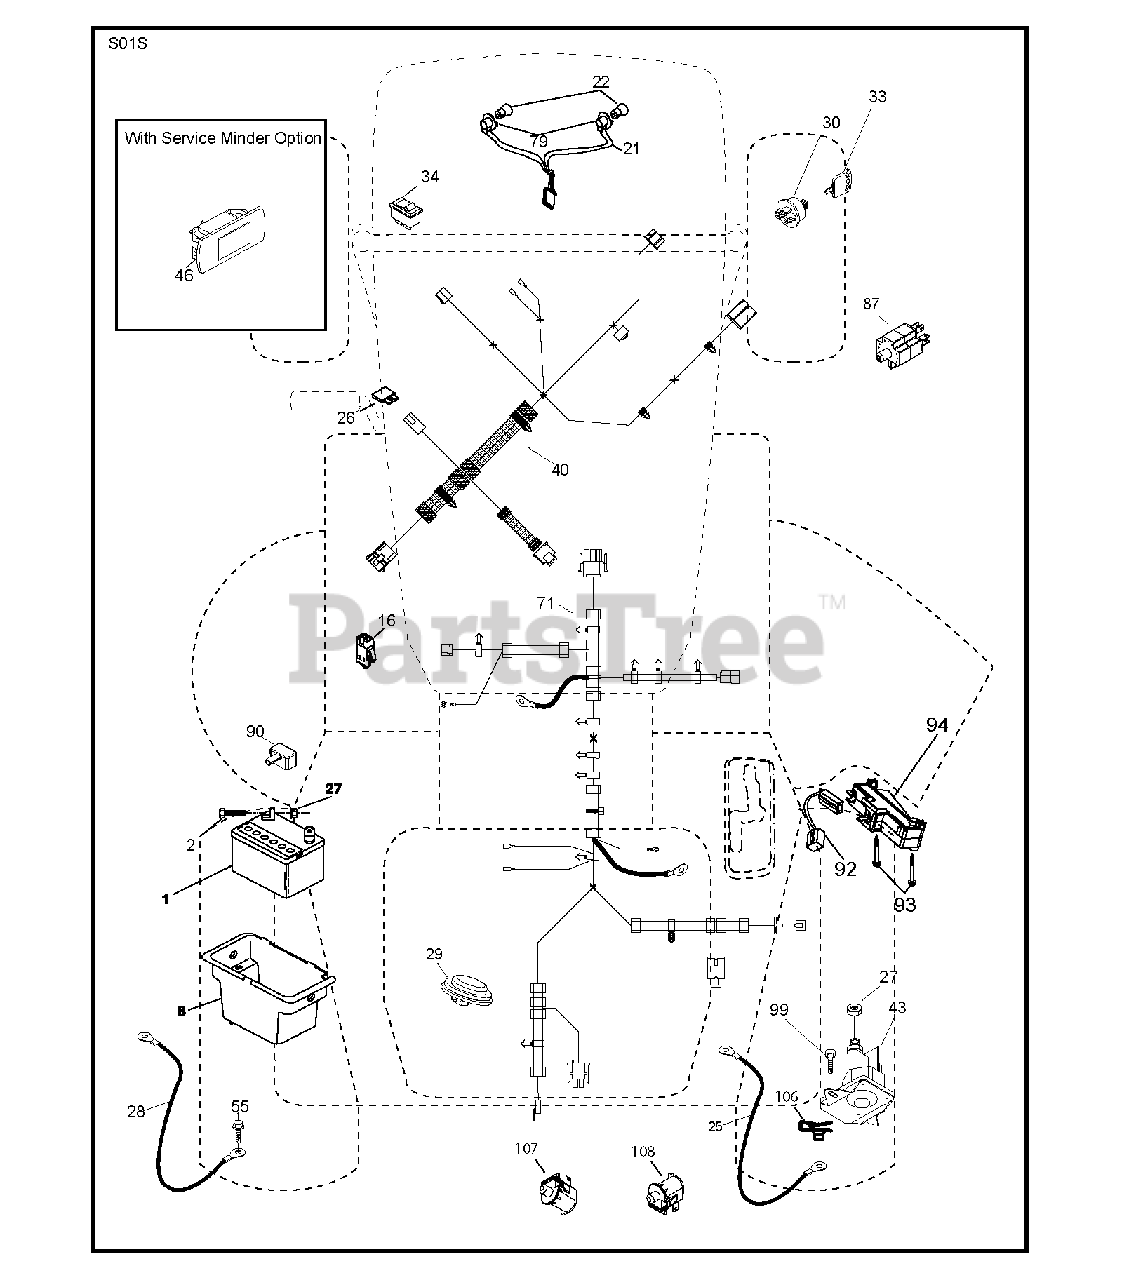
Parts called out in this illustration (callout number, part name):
8	BOX.BATTERY.LT/SRD
16	SWITCH INTERLOOK PUSH-IN
21	HARNESS ASSY LIGHT
25	CABLE.BATTERY.20.RED.8 AWG
27	NUT
28	Battery Ground Cable, Rear 8 Ga
29	SWITCH.SEAT.DELTA.OPC.
30	SWITCH.IGN.DELTA.W.LGH.ROS
33	KEY.CHAIN.BLISTER.PACK.GEN.INT
40	HARNESS.ELECTRICAL.DASH.SRD
43	SOLENOID.W/BRASS.PLUNG
55	SCREW 5/16"
71	HARNESS.ELECTRIC.CHASSIS.SRD
79	BULB HOLDER ASM.
87	Railmount Switch, No-Nc-Nc
90	COVER.TERMINAL.BATTERY
92	HARNESS.PIGTAIL.CONSLE
93	SCREW.PLASTITE
94	MODULE.REVERSE.ROS
99	SCREW HEXWSHR 1/4-20X3/4
107	Snapmount Switch, No #2
108	SWITCH.SNAPMOUNT.NC
